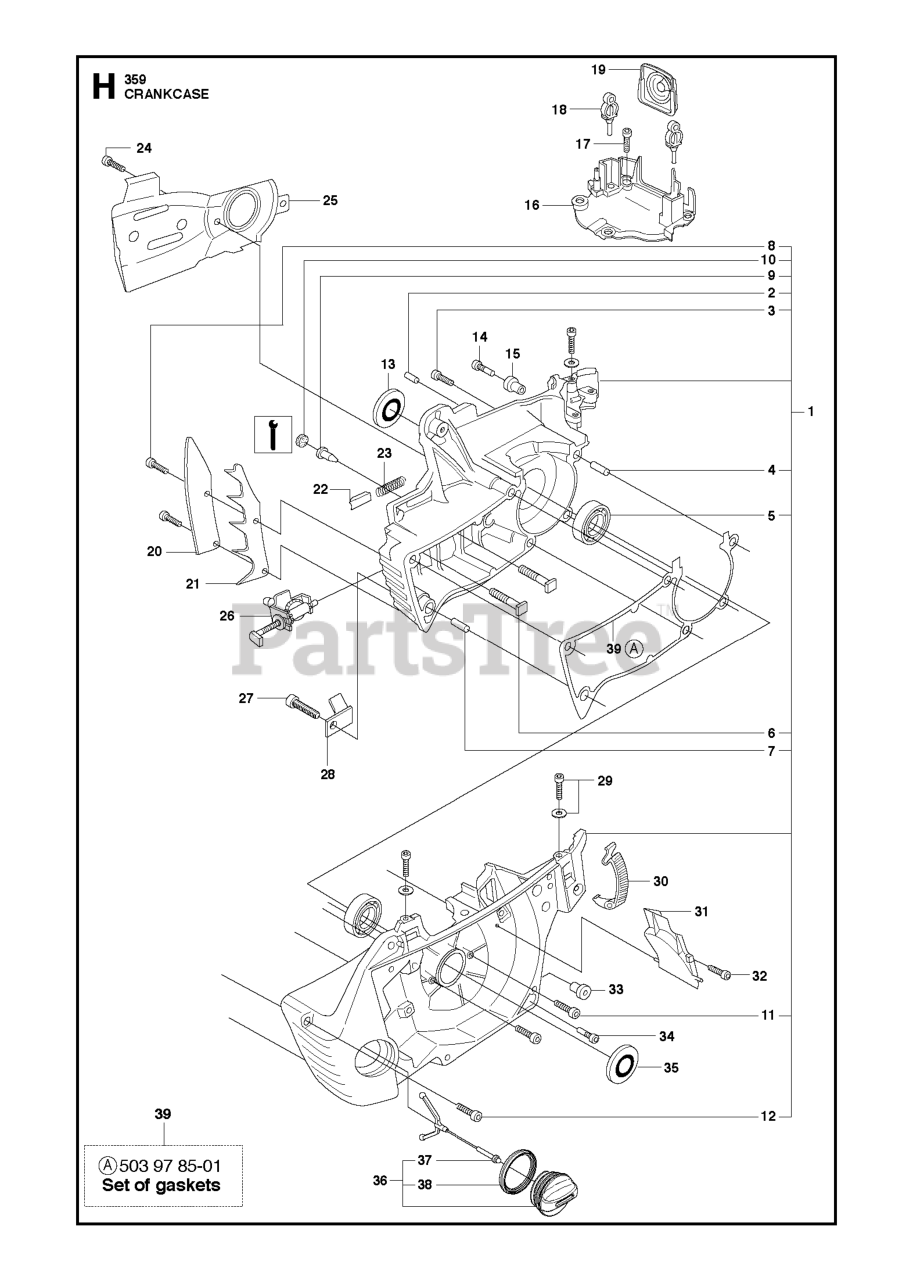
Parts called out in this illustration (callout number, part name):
1	CRANKCASE ASSY
5	BALL BEARING-6202-C3 SKF
9	VALVE-CHECK (DUCKBILL)
10	PLUG
15	MOVEMENT LIMITER
21	FELLING DOG
23	LOCK SPRING
26	CHAIN TENSIONER
28	CHAIN CATCHER
30	BUCKLE ORANGE
33	MOVEMENT LIMITER
36	TANK CAP
39	GASKET SET
